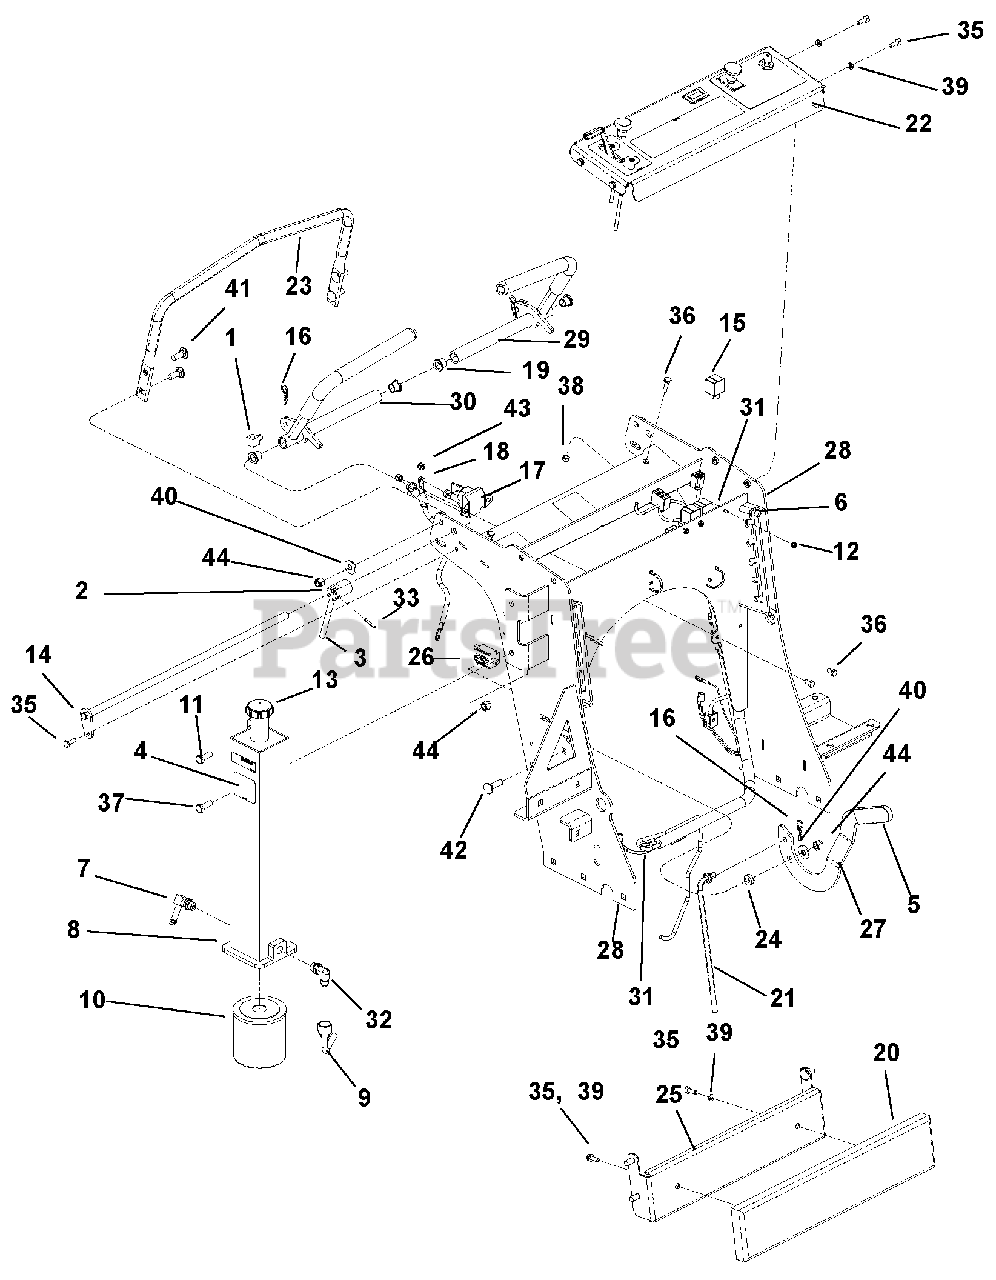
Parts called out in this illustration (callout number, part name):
1	SWIVEL
2	BASE, SPEED CONTROL LOCK
4	DECAL, HYDRO OIL RESERVOIR
5	GRIP
6	@BLT-HEX 8-32 X .5 YWZC
7	FTG-ADPTR .562-18 ST THD
8	RESERVOIR, HYDRAULIC WELDMENT
9	ELBOW FITTING
10	ELEMENT, OIL FILTER
11	DECAL, WARNING-HOT SURFACE (RE
12	#8.32 ELASTIC STOP NUT
13	CAP
14	SHAFT, PIVOT
15	RELAY, ISO MINI ELEC.
16	PIN, HAR .091X1.63 5/16-1/2 Y
17	SOLENOID, 12V STARTER
18	CABLE, 12" STARTER
19	BRG, FLG .500X.620X.500 BRNZ
20	PAD, THIGH
21	LINK, BRAKE Y
22	ASSEMBLY, CONTROL PANEL
23	HANDLE, SUPPORT
24	BUSHING, BRAKE PIVOT Y
25	WLDT, THIGH PAD BRACKET
26	SWITCH, NO-NO-NC GREY PLUNGER
27	BRAKE LEVER, OFFSET
28	WLDT, CONSOLE 34
29	WLDT, RH CONTROL LEVER
30	WLDT, LH CONTROL LEVER
31	HARNESS, WIRING
32	FTG, 90 9/16 MOR X 9/16 MJIC
33	Pin, Spring
34	BOLT, 1/4-20X.500 HEX 5 Y
35	BOLT, 1/4-20X.750 HEX 5 Y
36	BOLT, 1/4-20X1.00 HEX 5 Y
37	BOLT, 3/8-16X1.00 HEX 5 Y
38	QUICK START SHEET
39	WDMT,IDLER PIVOT RAPID XZ 52"
40	WASHER, .375 REG FLAT Y
41	BOLT, 3/8-16X1.00 CRG 5 Y
42	BOLT, 3/8-16X1.25 CRG 5 Y
43	LOCKNUT, 1/4-20 NYLOC Y
44	LOCKNUT, 3/8-16 NYLOC Y
